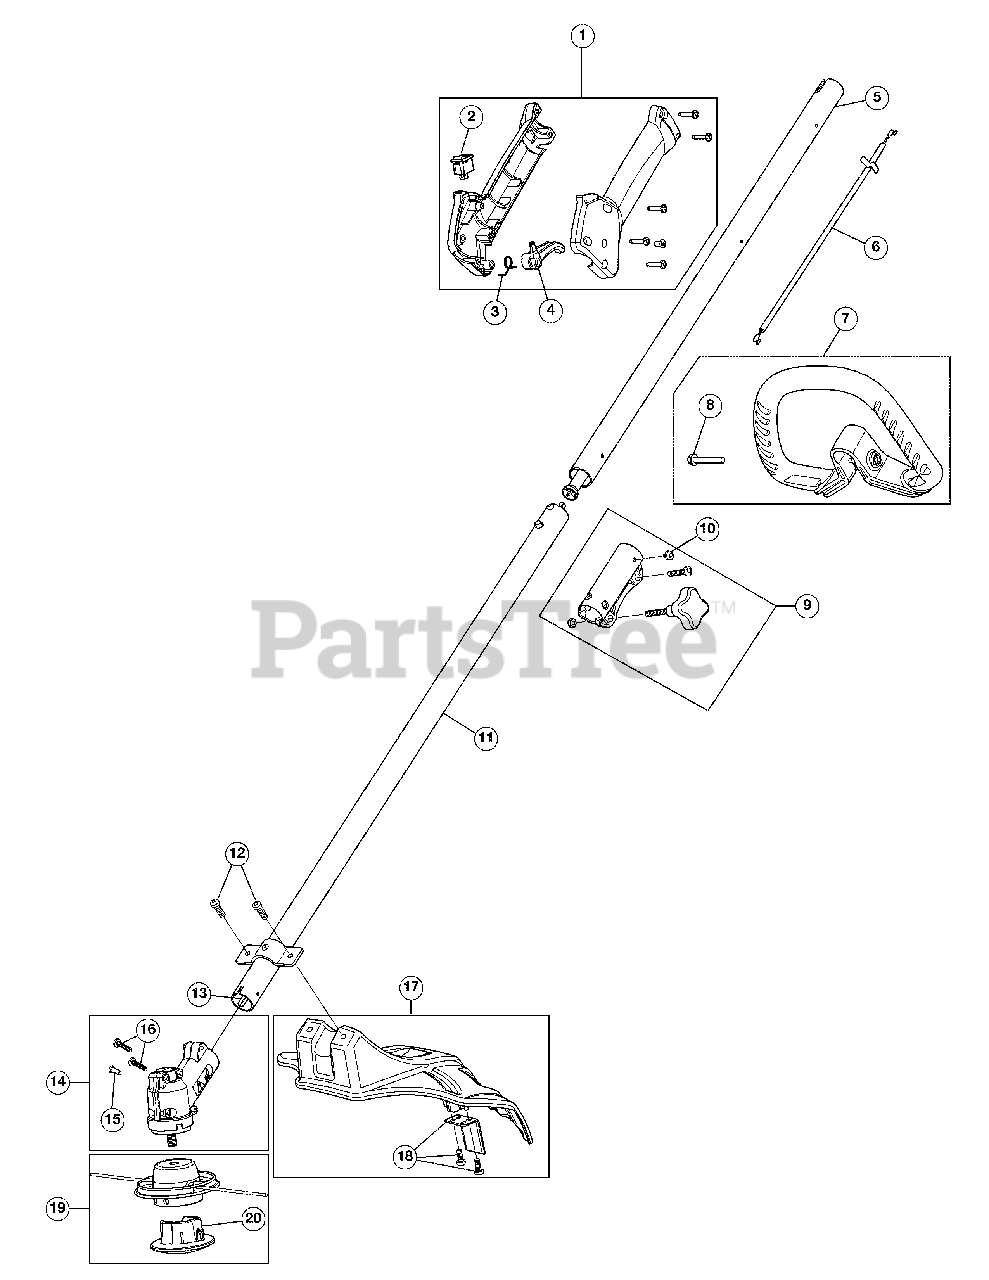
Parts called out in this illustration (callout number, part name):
1	Throttle Housing Assembly (Incl. 2 - 4)
2	Trigger Switch Assembly
3	Throttle Trigger Spring
4	Throttle Trigger
5	Upper Drive Shaft Assembly
6	Throttle Cable Assembly
7	D-Handle Assembly (Incl. 8)
9	Split Boom Coupler (Incl. 10)
10	Coupler Anti-Rotation Screw
11	Lower Drive Shaft Housing
12	Shield Mounting Screws
13	Lower Flexible Drive Shaft
14	Gearbox Assembly (Incl. 15 and 16)
15	Gearbox Anti-Rotation Screw
16	Gearbox Mounting Hardware
17	Shield Assembly (Incl. 18)
18	Blade Assembly
19	Cutting Head Assembly (Incl. 20)
20	Cutting Head Cap
